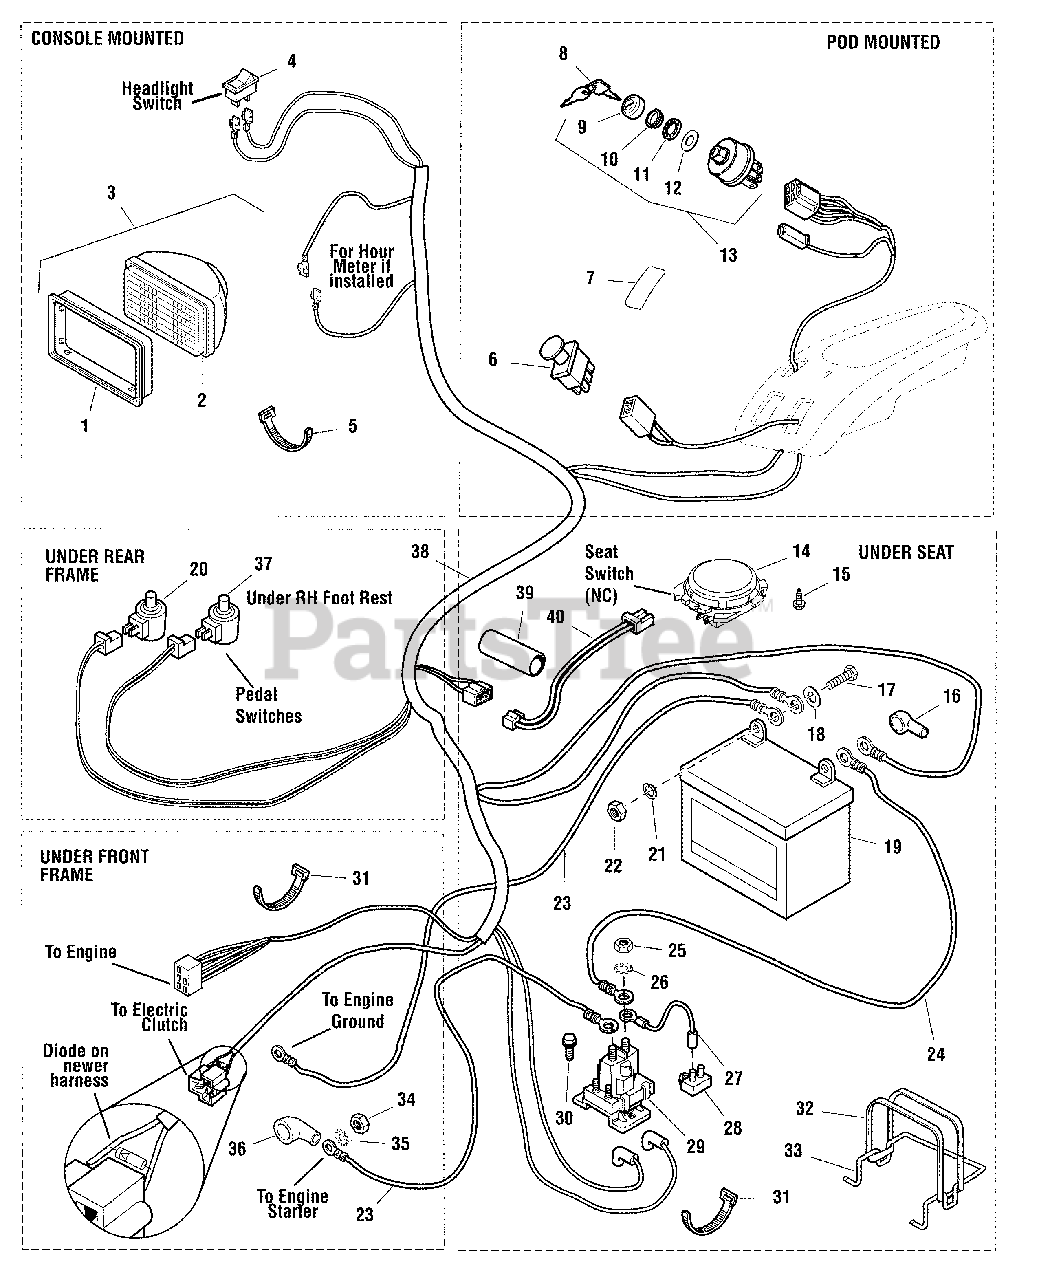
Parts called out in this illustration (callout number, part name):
1	BEZEL, Headlight
2	HEADLIGHT HOUSING
3	HEADLIGHT ASSEMBLY (Includes Ref. Nos. 1 & 2)
4	SWITCH, Rocker, Headlight
5	TIE, Self Locking, 3-5/8, Black
6	SWITCH, PTO, Push/Pull, w/Symbols
8	KEYS, Ignition
9	COVER, Ignition Switch
10	NUT, Hex, 5/8-32
11	LOCKWASHER, Intrnal Tooth, 5/8, Thin, Black
12	WASHER, 5/8, Thin, Black
13	SWITCH ASSEMBLY, Ignition (Includes Ref. Nos. 8, 9, 10, 11, & 13)
14	SWITCH, Seat, Gray Switch, Gray Retainer
14	SWITCH, Seat, Gray Switch, Black Retainer
15	CAPSCREW, Hex Head Plastite, 1/4-20 x 1/2
16	BOOT, Insulator
17	CAPSCREW, Hex Head, 1/4-20 x 3/4
18	WASHER, 1/4
19	BATTERY, 12 Volt
20	SWITCH, Push,Grey, Pedal Switch, (Domestic Only)
21	LOCKWASHER, 1/4
22	NUT, Hex, 1/4-20
23	CABLE, # 6 x 42-1/2" Long, 2 Ring Terminals
24	CABLE, # 6 x 10" Long, 2 Ring Terminals
25	NUT, Hex, 5/16-24
26	LOCKWASHER, External Tooth, 5/16
27	WIRE, 12GA, 6" Long Red
28	BREAKER, Circuit, 12Volt, 20Amps
29	SOLENOID, 4 Pole 12Volt
30	CAPSCREW, Hex Head Taptite, 14-20 x 5/8
31	TIE, Self Locking, 7-5/16 Long, Black
32	STRAP, Black Rubber
33	BRACE, Battery
34	NUT, Hex, 3/8-16
35	LOCKWASHER, External Tooth, 3/8
36	COVER, Terminal, Red
37	SWITCH, Push, Black, Pedal Switch
38	HARNESS, Wiring
39	SHRINK TUBE
40	WIRE ASSEMBLY, 16GA, 16" Long, Black/Tan
